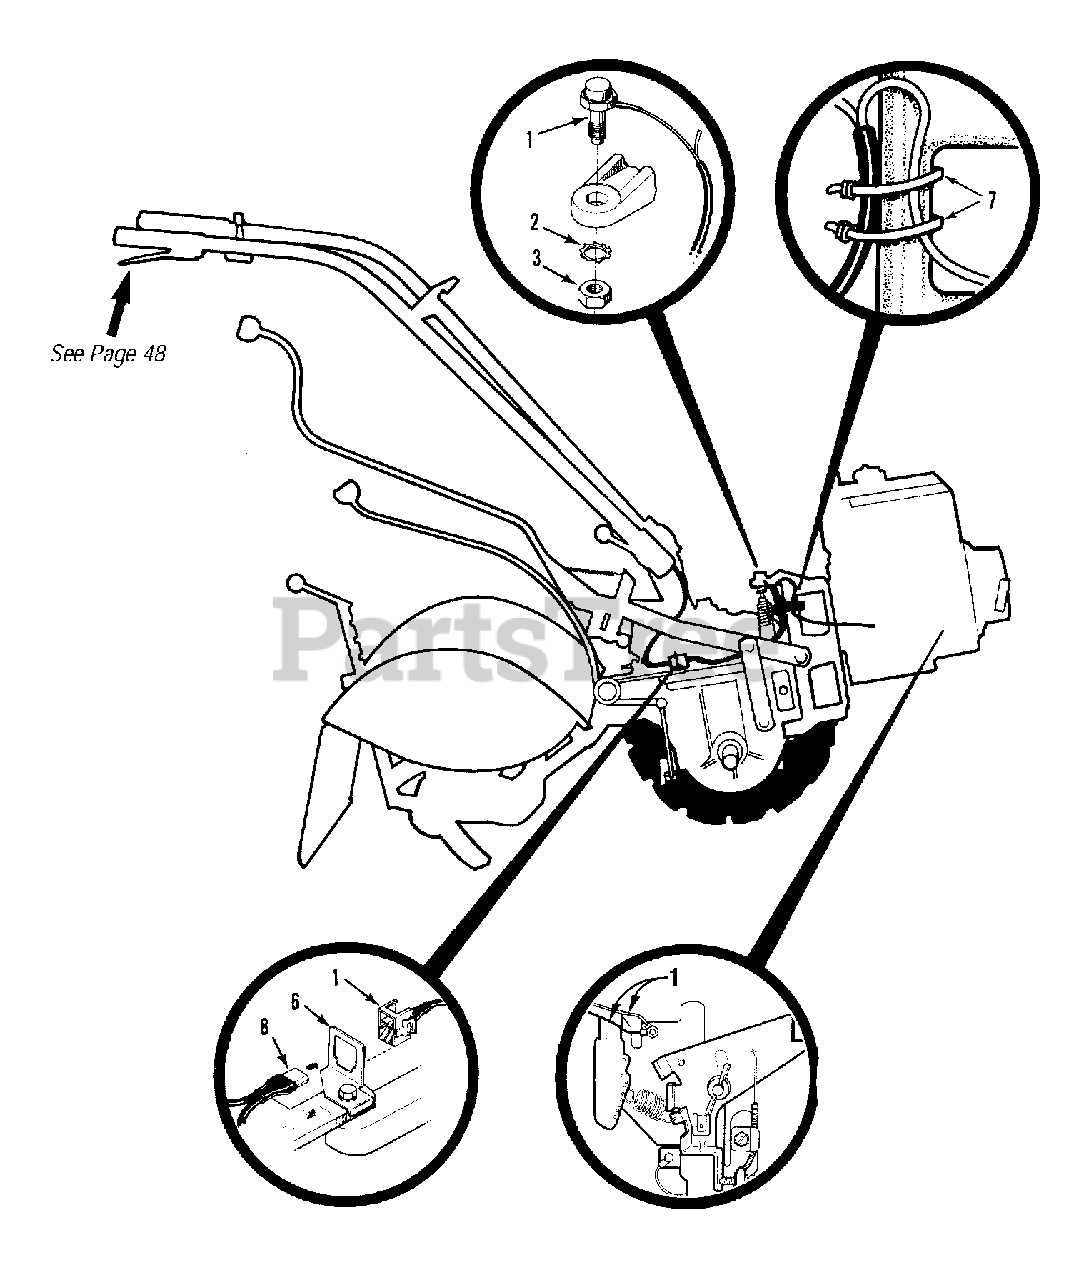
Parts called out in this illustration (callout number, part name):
1	Engine Wire Harness Assy-forward interlock system
2	Lockwasher-external tooth, 7/16"
3	Nut-hex, 7/16"-20
6	Clip-for plug connector
7	Tie-plastic
8	Handlebar Wire Harness Assy
